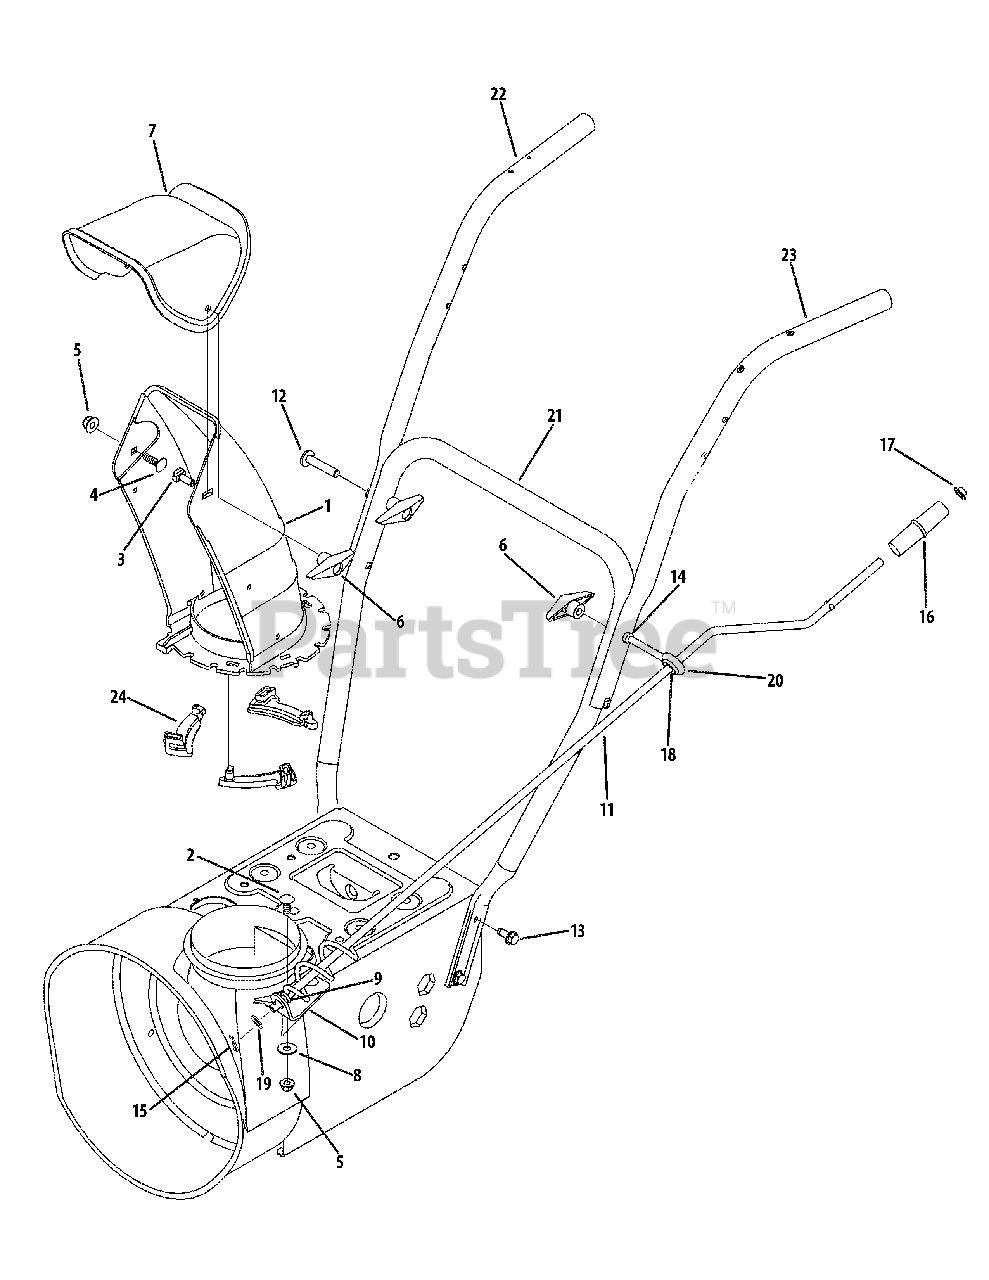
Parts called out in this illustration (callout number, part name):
1	Chute Assembly
2	Carriage Screw, 5/16-18 x 1.00
3	Carriage Bolt, 5/16-18 x 1.00
4	Carriage Bolt, 5/16-18 x .750
5	Flange Lock Nut, 5/16-18
6	Wing Knob
7	Upper Chute
8	Flat Washer, .349 x .879 x .063
9	Plastic Bushing, .380 ID
12	Carriage Screw, 5/16-18 x 2.25
13	Hex Washer Screw, 5/16-18 x .750
14	Hex Nut, 5/16-18
15	Cotter Pin, .072 x 1.13
16	Chute Crank Knob
17	Push Rod Cap, 3/8
18	Rubber Grom., .44 ID x .94 OD x .50
19	Flat Washer, .375 x .738 x .063
20	Chute Crank Eye Bolt, .70
24	Chute Flange Keeper
